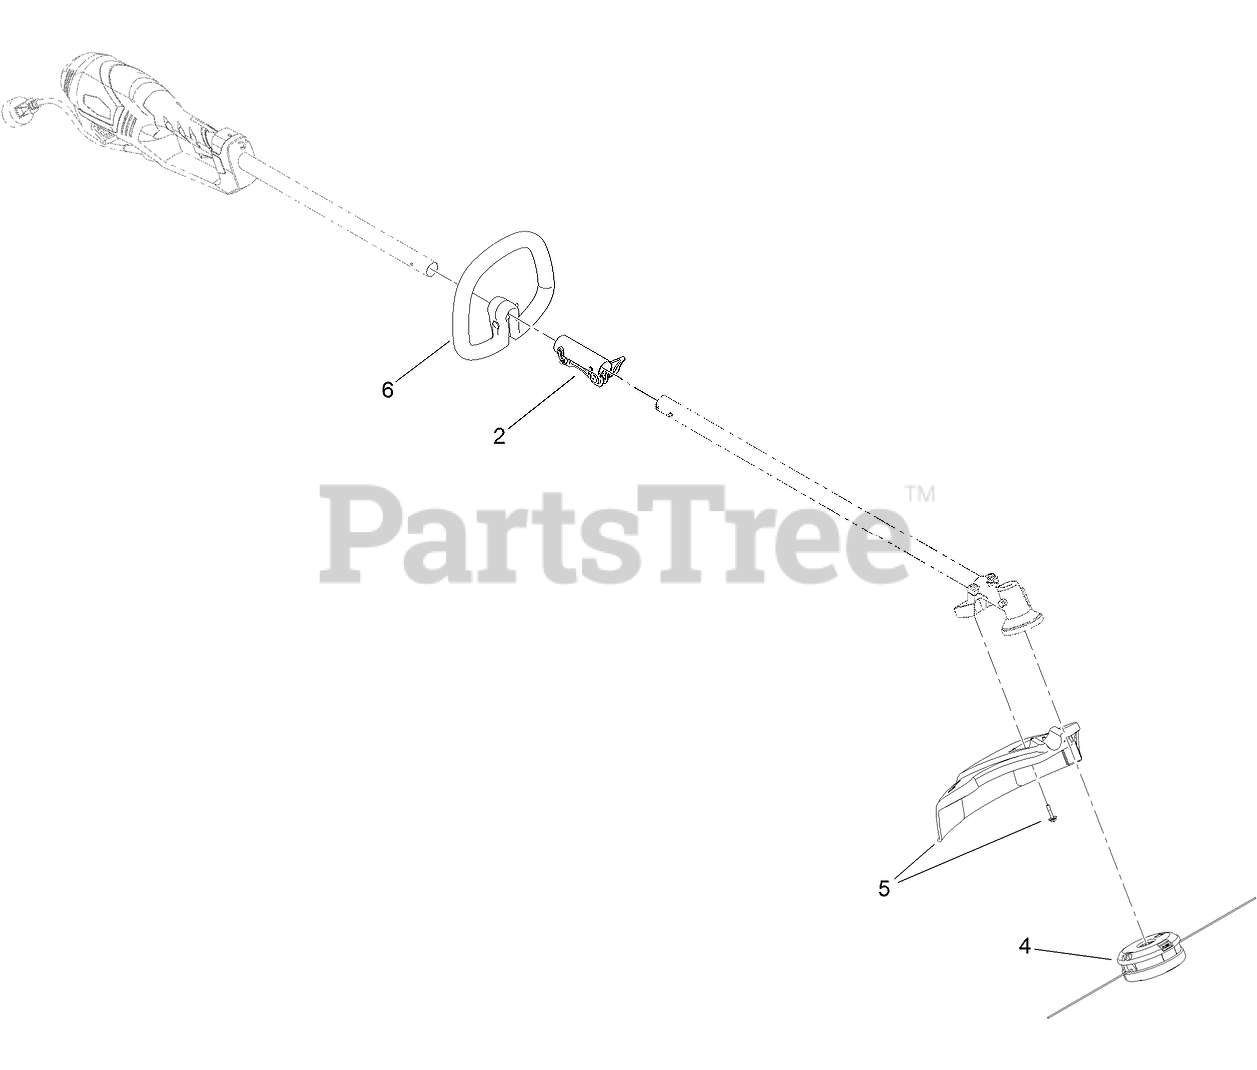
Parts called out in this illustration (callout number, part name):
2	SHAFT CLAMP ASM
4	BUMP FEED HEAD ASM
5	SHIELD-GRASS
6	HANDLE-TRIMMER
